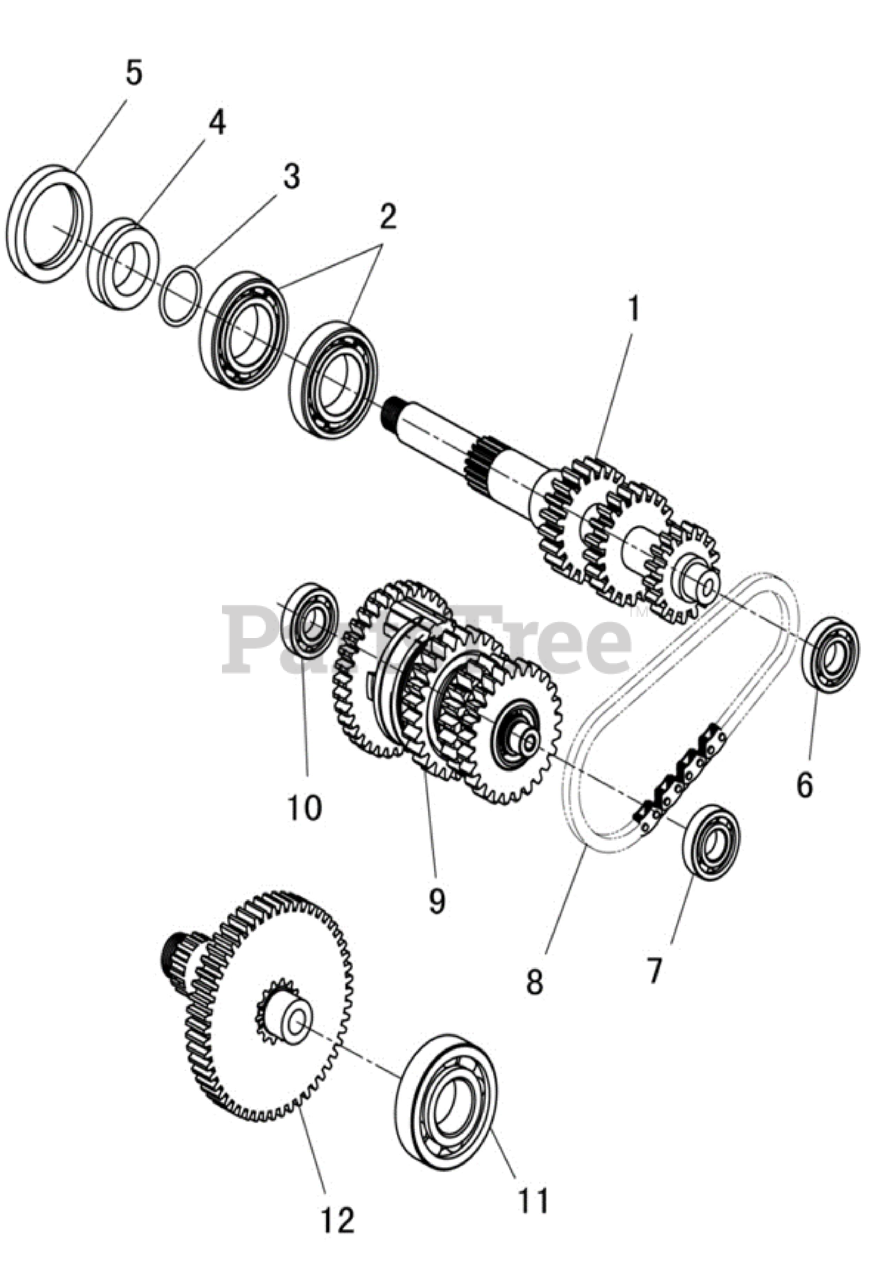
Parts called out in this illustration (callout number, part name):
1	Transmission Main Shaft
2	Bearing 6006C3
3	O-Ring 26.1X2.4
4	Secondary CVT Bushing
5	Oil Seal 42X55X8
6	Bearing 6203
7	Bearing 6202
8	tooth shaped chains for R gear
9	Transmision Countershaft Assy
10	Bearing 6203DLA8
11	Bearing 6303
12	X Driveshaft assy
